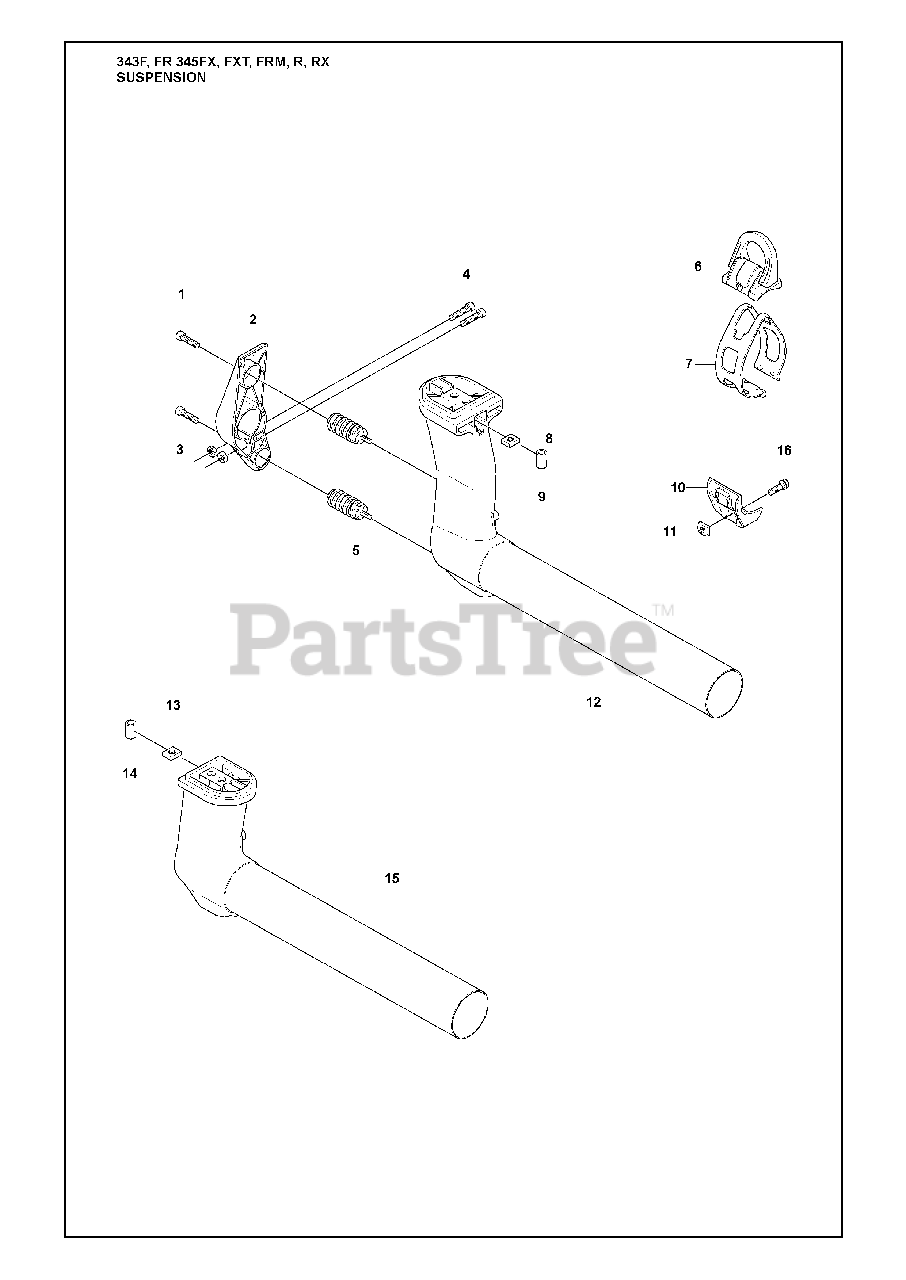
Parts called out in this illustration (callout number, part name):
2	HOLDER
6	LOOP
10	BRACKET, LOWER HANGER
11	SQUARE NUT M5
12	SUPPORT
15	SUPPORT
